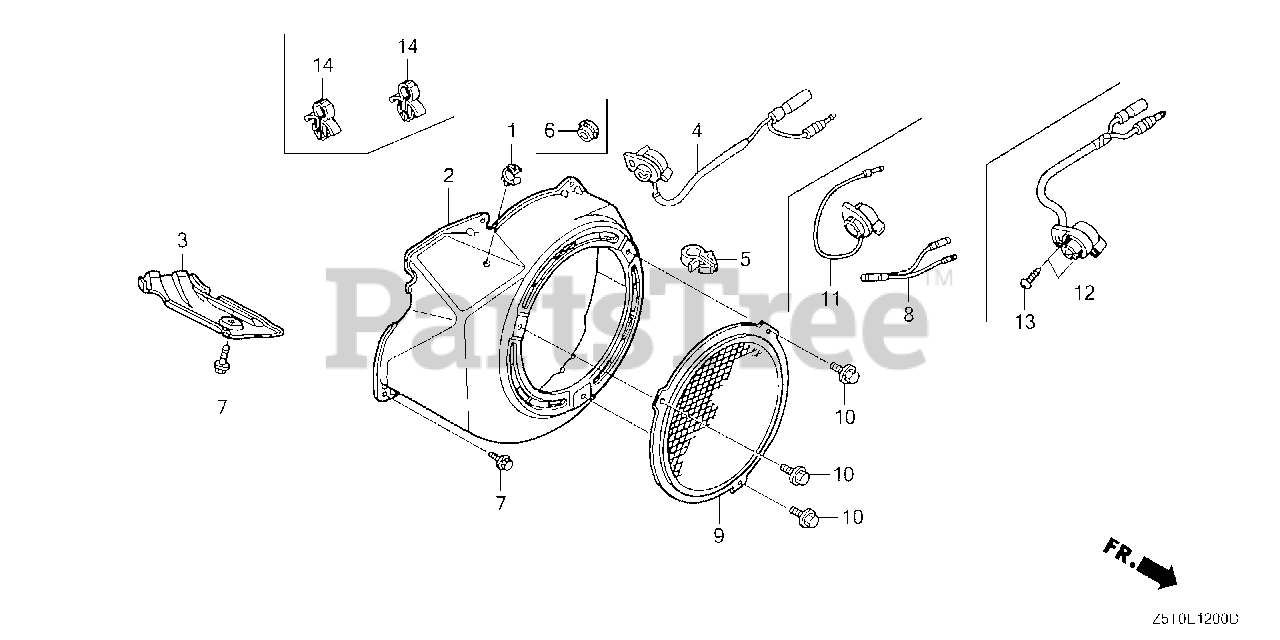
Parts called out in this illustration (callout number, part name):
1	CLIP, TUBE
2	COVER, FAN *NH1* (BLACK)
7	BOLT, FLANGE (6X12) (CT200)
12	SWITCH ASSY., ENGINE STOP
13	SCREW, TAPPING (3X6) (PO)
